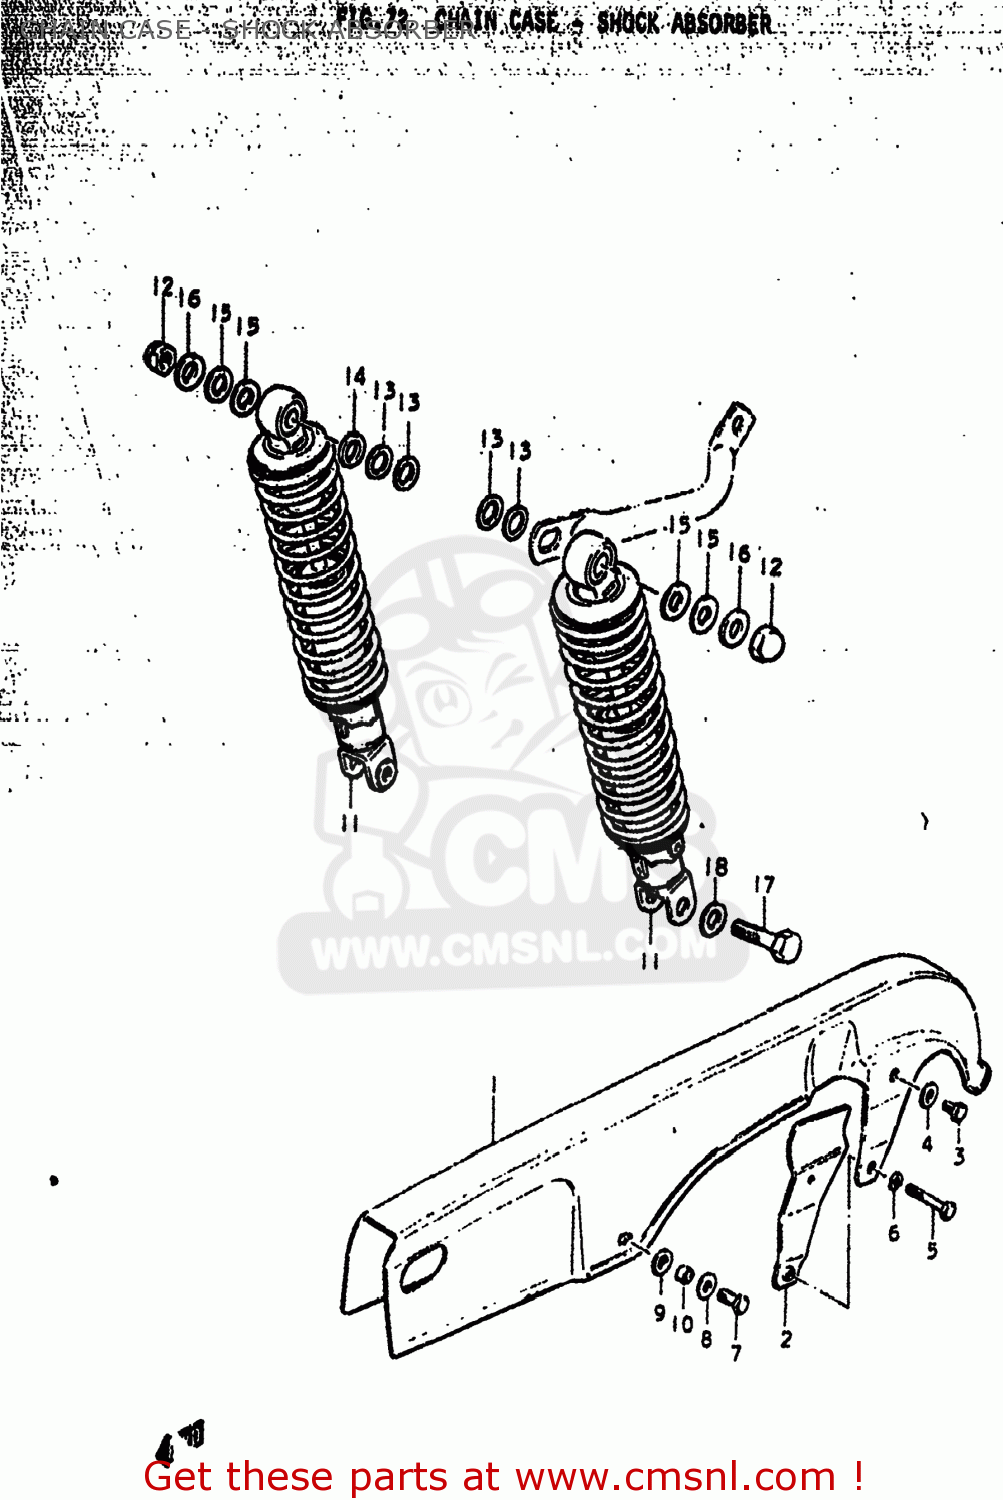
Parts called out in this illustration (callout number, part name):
1	CASE,CHAIN
2	REINFORCEMENT,CHAIN CASE
3	BOLT(6X8)
4	WASHER
5	BOLT
6	LOCK WASHER
7	BOLT
8	WASHER(6.5X18X1)
9	CUSHION
10	SPACER (6.1X8X5.2)
11	ABSORBER ASSEMBLY,REAR SHOCK
12	NUT, LOWER LH
13	WASHER
14	WASHER (12.5X24X3.2)
15	WASHER
16	WASHER(10.5X24X3.2)
17	BOLT(10X36)
18	WASHER
